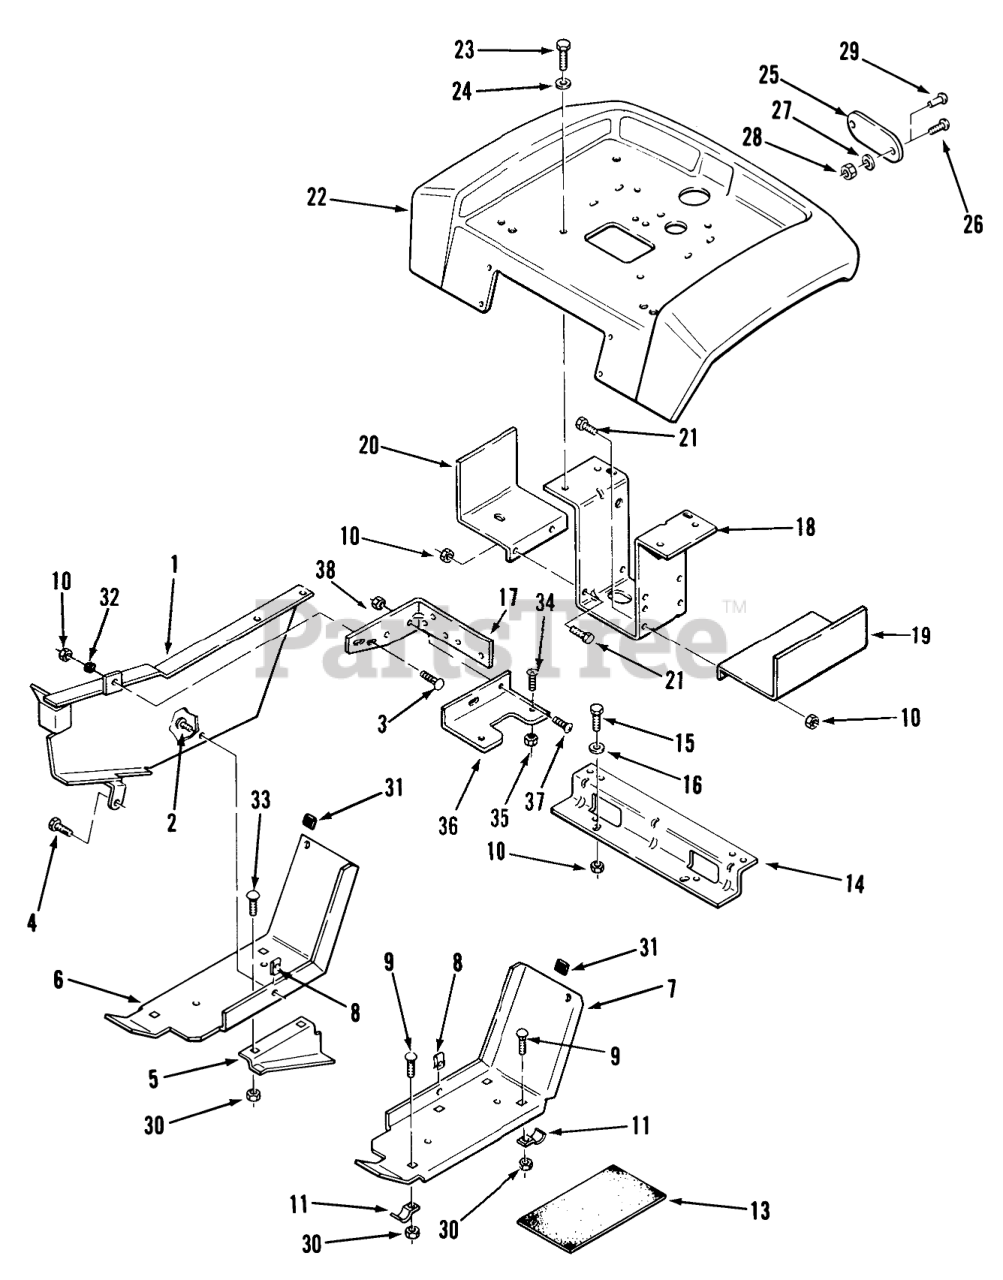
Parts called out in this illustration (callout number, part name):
1	Belt Guard
2	Screw
3	BOLT-CARR
4	SCREW
5	GUID-LOWER BLTR
6	Footrest-RH
7	FOOTREST LH R
9	BOLT-CARR
10	NUT-LOCK, NI
11	BRACKET
13	PAD FOOTREST
14	BRACKET-FENDER B
15	SCREW-HH
16	WASHER-PLAIN
17	BRACKET-BELTB
18	Bracket-Fender Support
19	Fuel Tank Support LH
20	Support-FueITank RH
21	SCREW-HH
22	Fender
23	SCREW
24	WASHER 5/16 SAE
25	Reflector
26	Screw
27	WASHER-LOCK
28	NUT-HEX
29	Poprivet
30	NUT-LOCK, NI
31	BUMPER SJ5514 BLACK
32	NUT-PUSH
33	BOLT-CARR 5/16 SN
35	Nut
36	BRKT-FUS HLDERB
37	SCREW-HH
38	NUT-LOCK, NI
